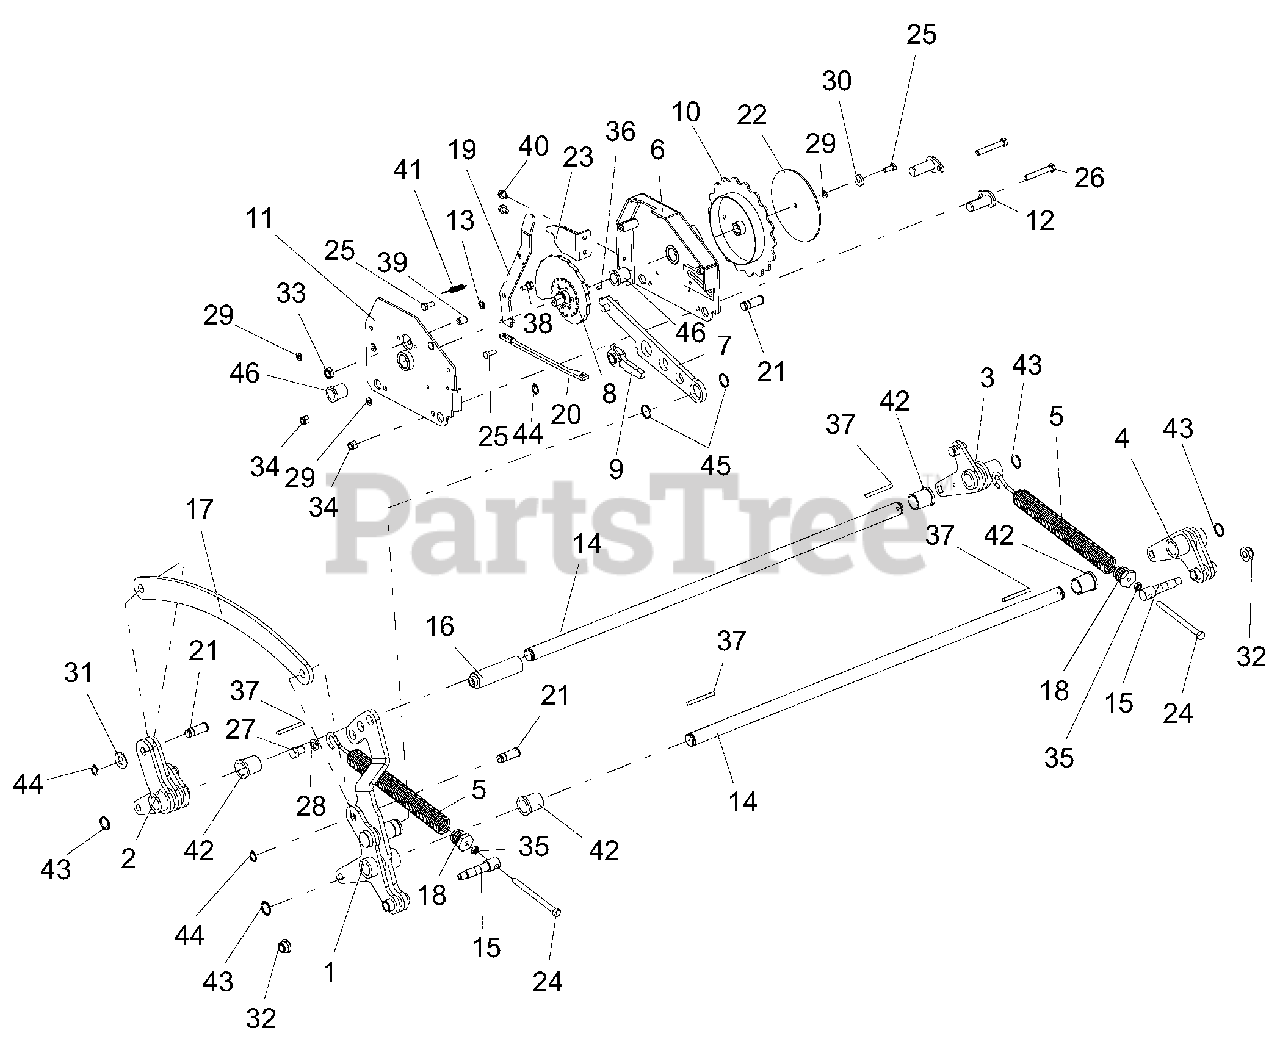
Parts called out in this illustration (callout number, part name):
1	WLDMT, LIFT PEDAL
2	WLDMT, LIF T
3	WLDMT, LIF T
4	WLDMT, LIF T
5	SPRG, DECK LIFT
6	WLDMT, HOC INNER
7	WLDMT, LINK
8	WLDMT, CAM HOC
9	WLDMT, LOCK PAWL
10	WLDMT, DIAL, HOC
11	WLDMT, HOC OUTER
12	WLDMT, PIN
13	WAVE, WASHER
14	SHAFT, FRONT MOWER LIFT
15	TRUNION, SPRG
16	PEDAL, LIFT
17	LIFT, LINK
18	PLUG, SPRG
19	LEVER, TRANSPORT LOCK
20	LINK, TRANSPORT LOCK
21	PIN, CLEVIS .625 SNAP RING
22	PLATE, DIAL-A-CUT
23	GUARD, DECK LIFT
24	BLT-HEX .38-16X5.0 GR5 FTD YWZ
25	BLT-HEX .31-18X.75 GR5 YWZC
26	BLT-HEX .38-16X2.50 GR5 YWZC
27	BLT-HEX .50-13X.75 GR5 YWZC
28	WSHR-LK .50X.125 REG YWZC
29	WSHR-LK .31X.078 REG YWZC
30	WSHR-FL-STL .328X.87X.179 YWZC
31	WSHR-FL-STL.656X1.31X.095 YWZ
32	NUT-LK-NYL-FLG .50-13 YWZC
33	NUT, 1/2-13 JAM GR5 y
34	NUT-LK-NYL .38-16 YWZC
35	NUT, 3/8-16 JAM GR5 Y
36	KEY-SQ .188X.188X.375
37	KEY-SQ .25 X 2.50 X .25 SAE
38	BOLT, SHLDR .38-16 x .437 HEX YZ
39	BALL SPRING PLUNGER, .500-13
40	SCR-TAP .31-18X.50 HWH TR YWZ
41	SPRING, EXT
42	BUSHING-FLANGE 1.00X1.25X1.50
43	RING-RETAINING-EXTERNAL 1.00X.078
44	RING-RETAINING-EXTERNAL .625X.050
45	RING-RETAINING-EXTERNAL 1.25X.050
46	BUSHING, .750 X 1.00 X .750
